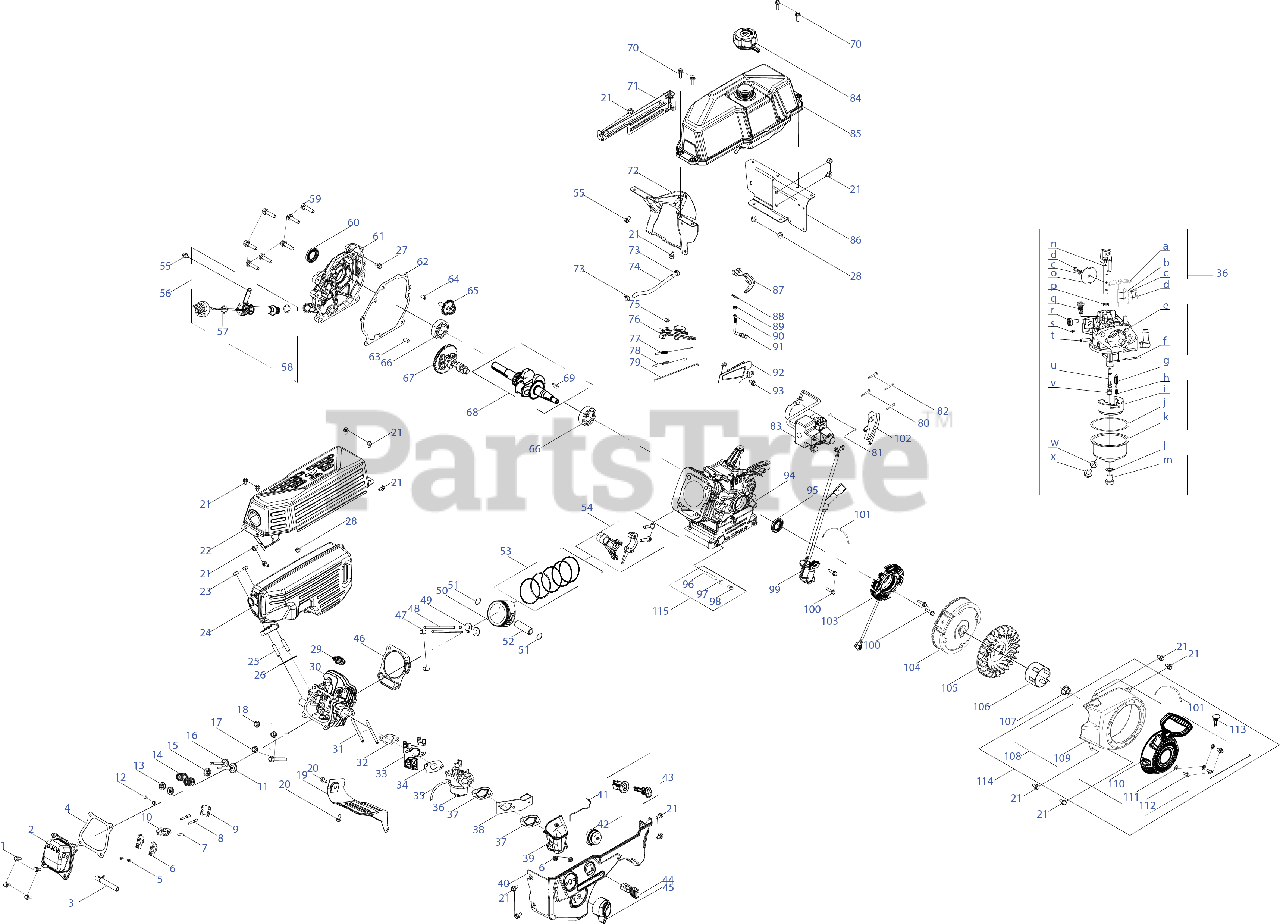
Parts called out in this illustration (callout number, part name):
1	BOLT M6 x 16
2	VALVE COVER
3	BREATHER HOSE
4	VALVE COVER GASKET
5	HEX NUT
6	ROCKER ARM ASSEMBLY
7	ROCKER ARM SHAFT
8	PIVOT BOLT
9	PUSH ROD GUIDE
10	ROCKER ARM PIVOT BLOCK
11	INTAKE VALVE
12	EXHAUST VALVE ADJUSTER
13	EXHAUST VALVE SPRING RETAINER
14	VALVE SPRING
15	INTAKE VALVE SEAL
16	EXHAUST VALVE
17	SCREW M10-1.25 x 65 x GR10.9
18	BOLT M10-1.25 x 70
19	AIR SHIELD
20	BOLT M6-1 x 12 GR8.8
21	BOLT-M6 x 12
22	MUFFLER GUARD
24	MUFFLER
25	STUD M8-1.25 x 36
26	MUFFLER GASKET
27	SCREW M6-1 x 20 CL5.8
28	HEX NUT
29	SPARK PLUG
30	CYLINDER HEAD
31	STUD M6 x 92
32	CARBURETOR INSULATOR GASKET
33	CARBURETOR INSULATOR
34	CARBURETOR GASKET
35	PRIMER HOSE
36	CARBURETOR ASSEMBLY
37	CARBURETOR GASKET PLATE
38	CHOKE CONTROL
39	HEATER BOX
40	CONTROL PANEL
41	PUSH ROD
43	ENGINE KEY SWITCH ASSEMBLY
44	THROTTLE CONTROL KNOB
45	CHOKE LEVER
46	CYLINDER HEAD GASKET
47	PIN, 12x16
48	PUSH ROD (SINGLE)
49	TAPPET
50	PISTON
51	PISTON PIN SNAP RING
52	PISTON PIN
53	PISTON RING SET
54	CONNECTING ROD ASSEMBLY
55	BOLT-M6 x 16
56	DIPSTICK ASSEMBLY
57	DIPSTICK O-RING
58	O-RING 15.8 x 2.5
59	BOLT M8-1.25 x 32 GR5.8
60	OIL SEAL
61	CRANKCASE COVER
62	CRANKCASE COVER GASKET
63	DOWEL PIN
64	DOWEL PIN
65	GOVERNOR GEAR/SHAFT ASSEMBLY
66	BALL BEARING
67	CAMSHAFT
68	CRANKSHAFT ASSEMBLY
69	FLYWHEEL KEY
70	BOLT-M6 x 22
71	FUEL TANK INSULATOR
72	FRONT FUEL TANK BRACKET
73	HOSE CLAMP
74	FUEL LINE
75	BOLT M6-1 x 12 GR8.8
76	GOVERNOR GEAR BRACKET
77	GOVERNOR SPRING
78	THROTTLE RETURN SPRING
79	GOVERNOR ROD
80	BOLT M6-1 x 32 GR8.8
81	DOWEL PIN
82	BOLT-M4 x 55
83	ELECTRIC STARTER
84	FUEL CAP
85	FUEL TANK
86	FUEL TANK INSULATOR
87	GOVERNOR LEVER
88	COTTER PIN
89	GOVERNOR SEAL
90	O-RING
91	GOVERNOR SHAFT
92	AIR FLOW SHIELD
93	BOLT M6-1 x 10 GR8.8
94	CRANKCASE
95	OIL SEAL
96	OIL DRAIN PIPE
97	WASHER
98	OIL DRAIN PLUG
99	IGNITION MODULE
100	BOLT M6-1 x 25 GR8.8
101	CABLE TIE - 3 x 150
102	LOWER SHIELD
103	IGNITION MODULE
104	FLYWHEEL
105	COOLING FAN
106	STARTER CUP
107	FLYWHEEL NUT
108	RECOIL HOUSING ASSEMBLY
109	BLOWER HOUSING
110	RECOIL STARTER ASSEMBLY
111	RECOIL FLAT WASHER
112	HEX FLANGE BOLT M6-1 x 10 GR8
113	IGNITION KEY
114	RECOIL STARTER
115	OIL DRAIN ASSEMBLY
